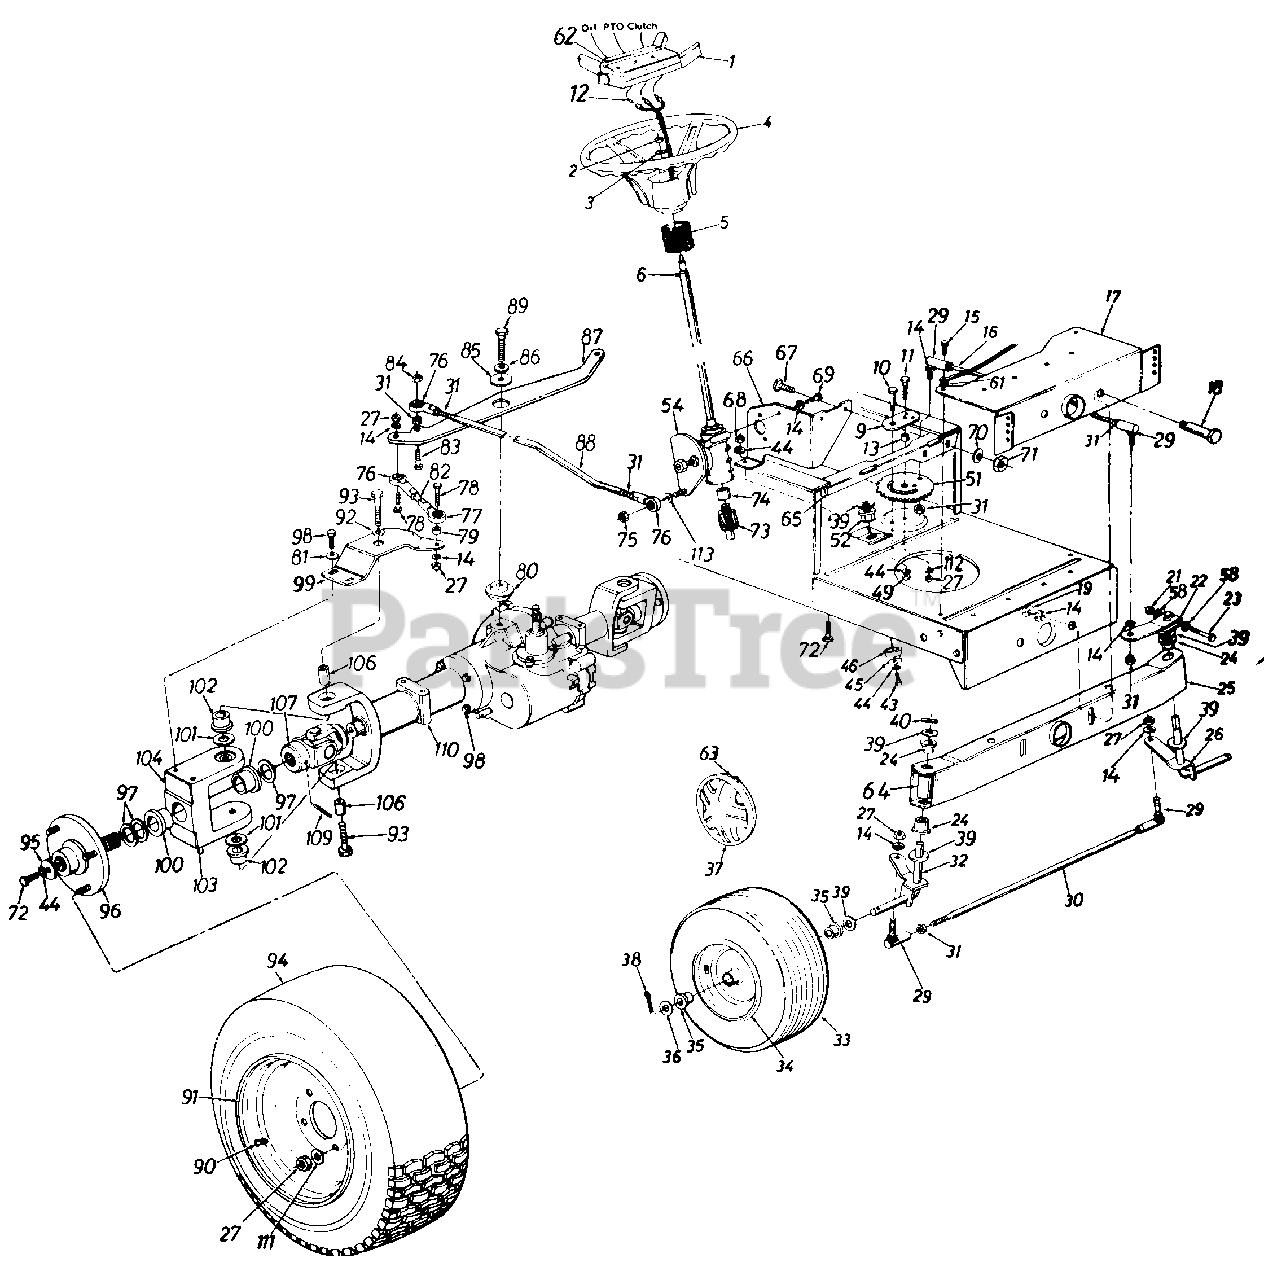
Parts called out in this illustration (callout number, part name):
1	Steering Wheel Insert
2	Hex L-Nut 5/16-24 Thd.
3	Belleville Wash. .345" I.D.
4	Steering Wheel
5	Steering Bellow
6	Steering Shaft Ass'y.
9	Retainer Plate
10	Shoulder Bolt .437" Dia. x .35" Lg. 5/16-18 Thd.
11	Hex Bolt 3/8-24 x 1.0" Lg. (Grade 5)
12	Bulb
13	Spacer .380" I.D. x.625" O.D. x .227"
14	L-Wash. 3/8" I.D.
15	Hex Wash. Hd. Self-Tap Scr.
16	Steering Drag Link
17	Front Pivot Brkt.
18	Shoulder Bolt .498" Dia. x 2.04" Lg. 3/8-16 Thd.
19	Hex Nut 3/8-16 Thd.
21	Hex Cent. L-Nut 5/16-24 Thd.
22	Steering Arm Front Axle
23	Hex Bolt 5/16-24 x 2.00" Lg. (Grade 5)
24	Hex Flg. Brg. .634" I.D.
26	Front Axle Ass'y. L.H.
27	Hex Nut 3/8-24 Thd.
29	Ball Joint 3/8-24 Thd.
30	Tie Rod
31	Hex Jam Nut 3/8-24 Thd.
32	Front Axle Ass'y. R.H.
33	Wheel Ass'y. Comp.
34	Front Wheel Rim Only
35	Flange Bearing
36	Fl-Wash. .635" I.D. x 1.59" O.D.
37	Front Hub Cap
38	Cotter Pin 1/8" Dia. x 1.25" Lg.
39	Fl-Wash. .640" I.D. x .24" O.D.
40	Spring Roll Pin
43	Hex L-Bolt 5/16-18 x .62"
44	L-Wash. 5/16" I.D.
45	Fl-Wash. .33" I.D. x 1.25" O.D.
46	Spacer (Plastic)
49	Hex Nut 5/16-18 Thd.
51	Steering Gear Segment
52	Hex Flg. Brg. .634 I.D.
54	Steering Ass'y. Comp.
58	Wave Wash. .32" I.D. x .62"
61	Ext. L-Wash. 5/16" I.D.
62	Steering Wheel Insert Label
63	Spring Clip
64	Plastic Tube
65	Horizontal Cross Bracket
66	Vertical Mounting Bracket
67	Hex Bolt 1/4-28 x .75" Lg.
68	Hex Nut 5/16-24 Thd.
69	Hex Bolt 3/8-16 x 1.0" Lg.
70	Bell-Wash. .265" I.D. x .75"
71	Hex Nut 1/4-28 Thd.
72	Hex Bolt 5/16-24 x .75" Lg.
73	Pinion Shaft
74	Steering Shaft Splined Coupler
75	Hex L-Nut 3/8-24 Thd.
76	Rod End 3/8-24 Thd. R.H.
77	Rod End 3/8-24 Thd. L.H.
78	Hex Bolt 3/8-24 x 1.5" Lg. (Grade 5)
79	Spacer .38" I.D. x .625"
80	Shld. Spacer .51" I.D.
81	Bell-Wash. .38" I.D. x .88"
82	Tie Rod
83	Hex Bolt 3/8-24 x 1.25" Lg.
84	Hex Patch L-Nut 3/8-24 Thd.
85	Fl-Wash. .531" I.D. x 1.75"
86	Bell-Wash. .505" I.D. x 1.0"
89	Hex Bolt 1/2-13 x 1.5" Lg. (Grade 5)
90	Air Valve
93	Hex Bolt 1/2-20 x 1.75" Lg. (Grade 5)
95	Fl-Wash. .33" I.D. x 1.25"
96	Wheel Flange Ass'y.
97	Fl-Wash. 1.0" x 1.56"
98	Hex Bolt 3/8-24 x 1.25" Lg.
101	Fl-Wash. .76" I.D. x 1.5"
102	Flange Brg. 3/4" I.D.
103	Grease Fitting
104	Wheel Brg. Housing
106	Pivot Sleeve
107	U-Joint
109	Grooved Roll Pin 1.0" Lg.
110	Axle Horn Ass'y.
111	Bell-Wash. .38" I.D. x .88"
112	Bell-Wash. .39" I.D. x 1.38"
113	Fl-Wash. .385" I.D. x .62"
